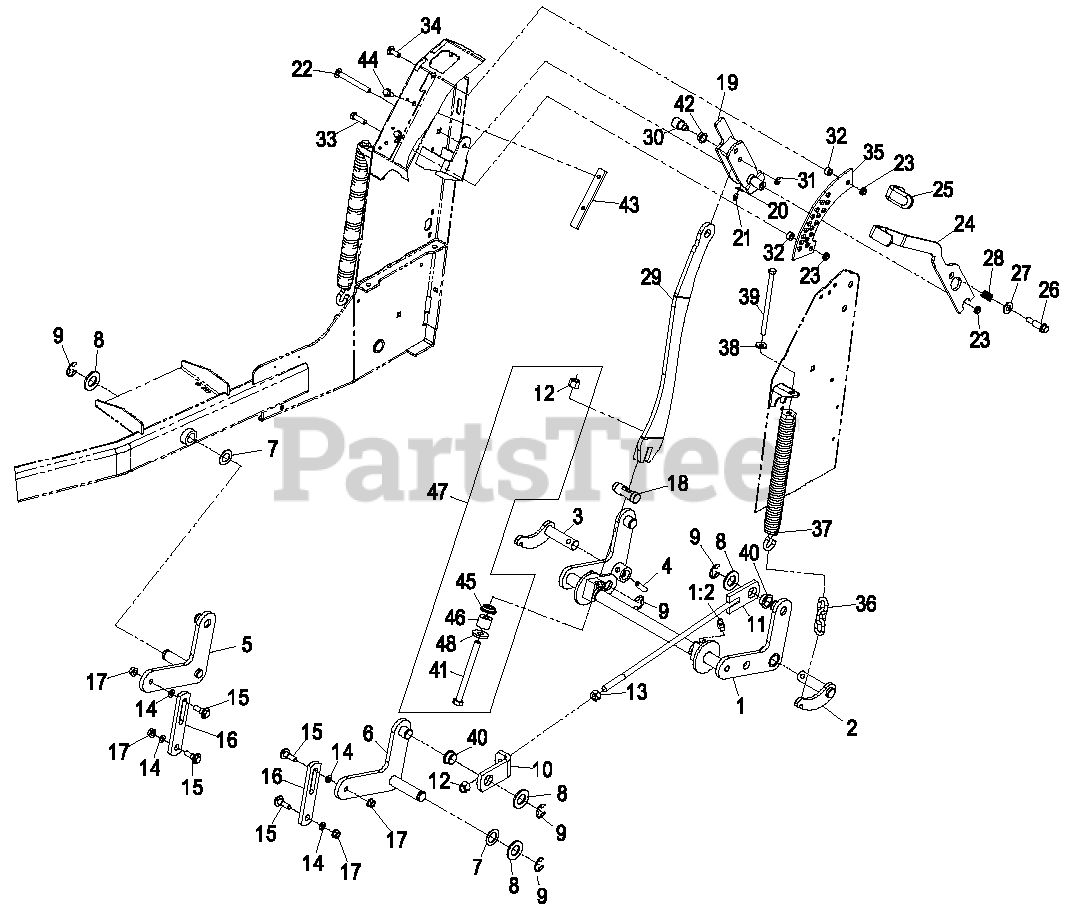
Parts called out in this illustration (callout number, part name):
1	REAR CROSSSHAFT ASM
1:2	FITTING-LUBE, 45 DEG
2	SHAFT-PIVOT, LH
3	SHAFT-PIVOT, RH
4	PIN-SPIRAL
7	WASHER-THRUST
8	WASHER-FLAT
9	RING-RETAINING, EXT
10	BRACKET-LIFT ROD
11	LIFT ROD ASM
12	NUT-LOCK, NI
13	NUT-HH
15	SCREW-SHOULDER, HHF
16	LINK-LIFT
18	PIN-HOC
19	HOC HANDLE ASM
20	WASHER-FLAT
21	FITTING-GREASE
22	SCREW-CARR
24	LEVER-HOC
25	GRIP-LEVER
26	SCREW-SHOULDER
27	WASHER-FLAT
29	BAR-LIFT
30	HUB-PIVOT
31	RING-RETAINING
32	SPACER
33	SCREW-HH
34	SCREW-CARR
35	BRACKET-HOC
36	CHAIN-DECKLIFT
37	SPRING-EXTENSION
38	WASHER-BELLEVILLE
39	BOLT-TAP, HH
40	BEARING-FLANGE
41	SCREW-HH
42	BEARING-FLANGE
43	SKID-HANDLE, LIFT
44	SCREW-THD ROLL, HWH
45	SEAT-SPRING
46	SPRING-URETHANE
47	HOC BOLT ASM
